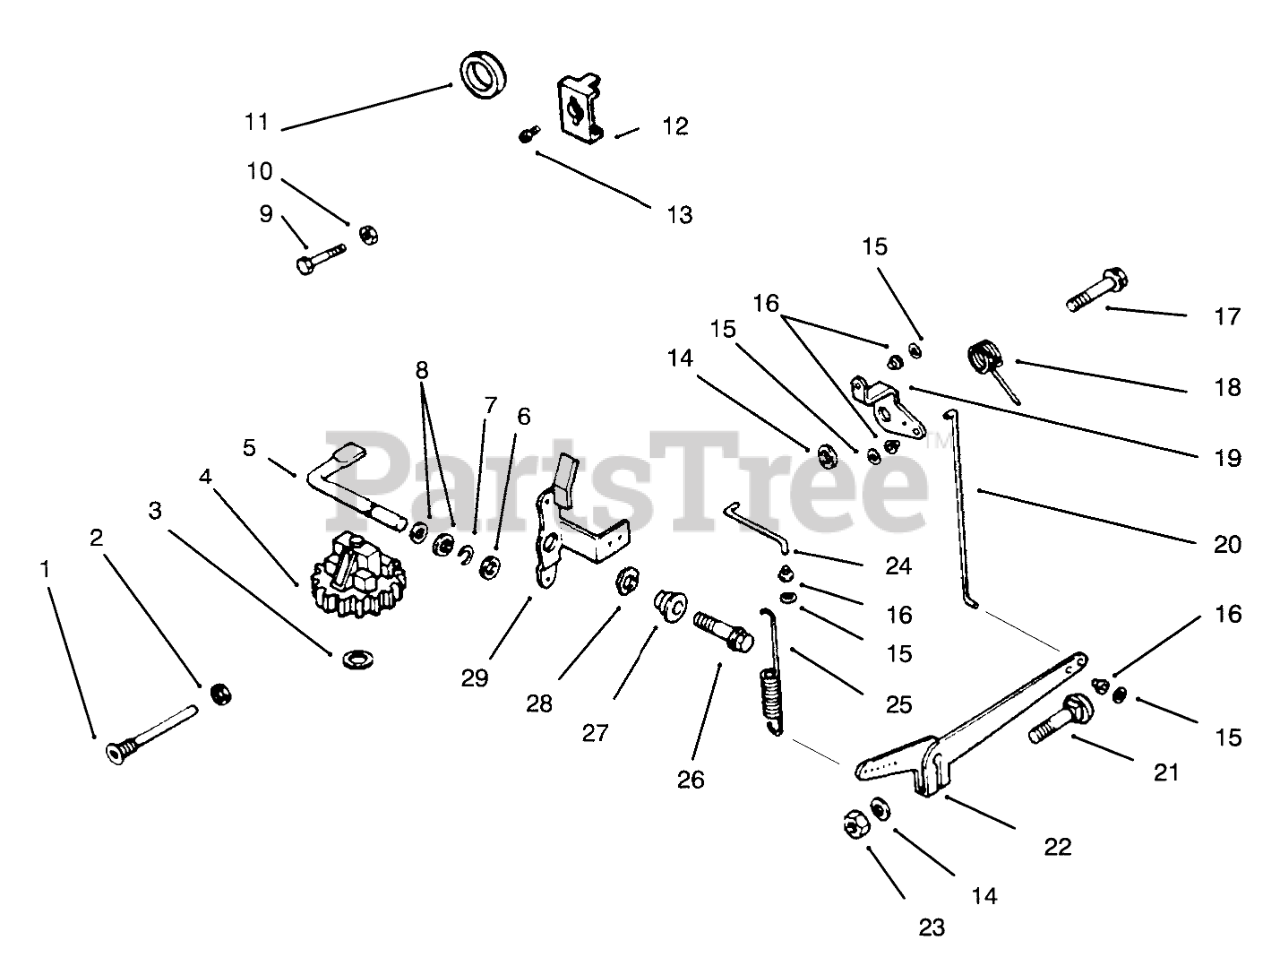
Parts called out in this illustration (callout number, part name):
1	Pin-GovemorStop
2	Washer
3	Washer
4	Governor Gear
5	Shaft-Govenor
6	Washer
7	Retainer-Governor
8	Washer
9	Screw-Hex Hd.
13	Screw
14	Washer
16	Bushing
17	Screw-Hex Wash. Hd.
18	Spring-Torsion
19	Lever-Throttle
20	Linkage-Governor
22	ARm-Governor
24	Linkage-Throttle
25	Spring-Governor (Only On: 72042, 72063, 72062, 72043)
26	Screw-Hex Washer Hd.
27	Bushing-Throttle Control
28	Washer
29	Lever-Speed Control
